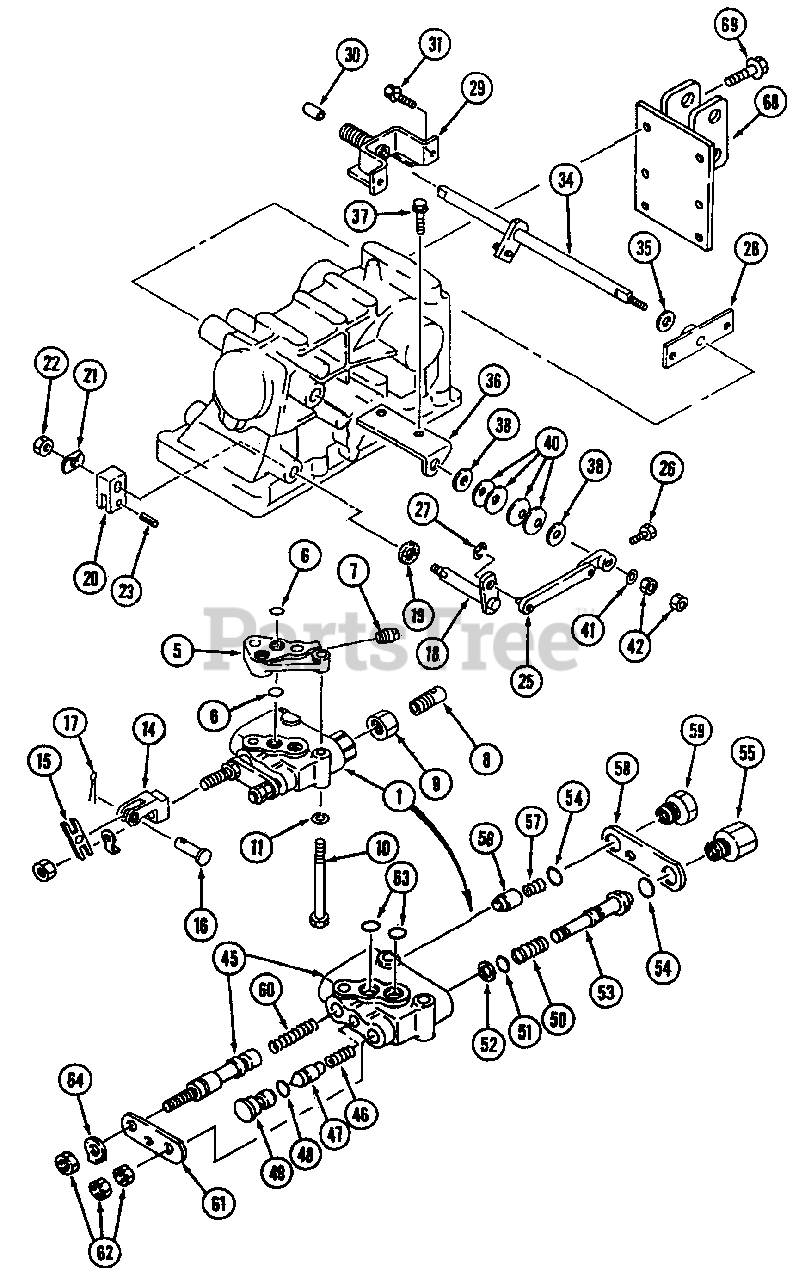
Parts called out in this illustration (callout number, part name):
1	Valve, Control
17	Pin, Split
20	Shifter, Valve
26	Bolt, W/Washer
31	Bolt, W/Washer
38	Liner
40	Spring, Conical
52	Ring, Back Up
56	Valve, Unloader
57	Spring
60	Spring, Return
68	Bracket, Top Link
69	Bolt, W/Washer
